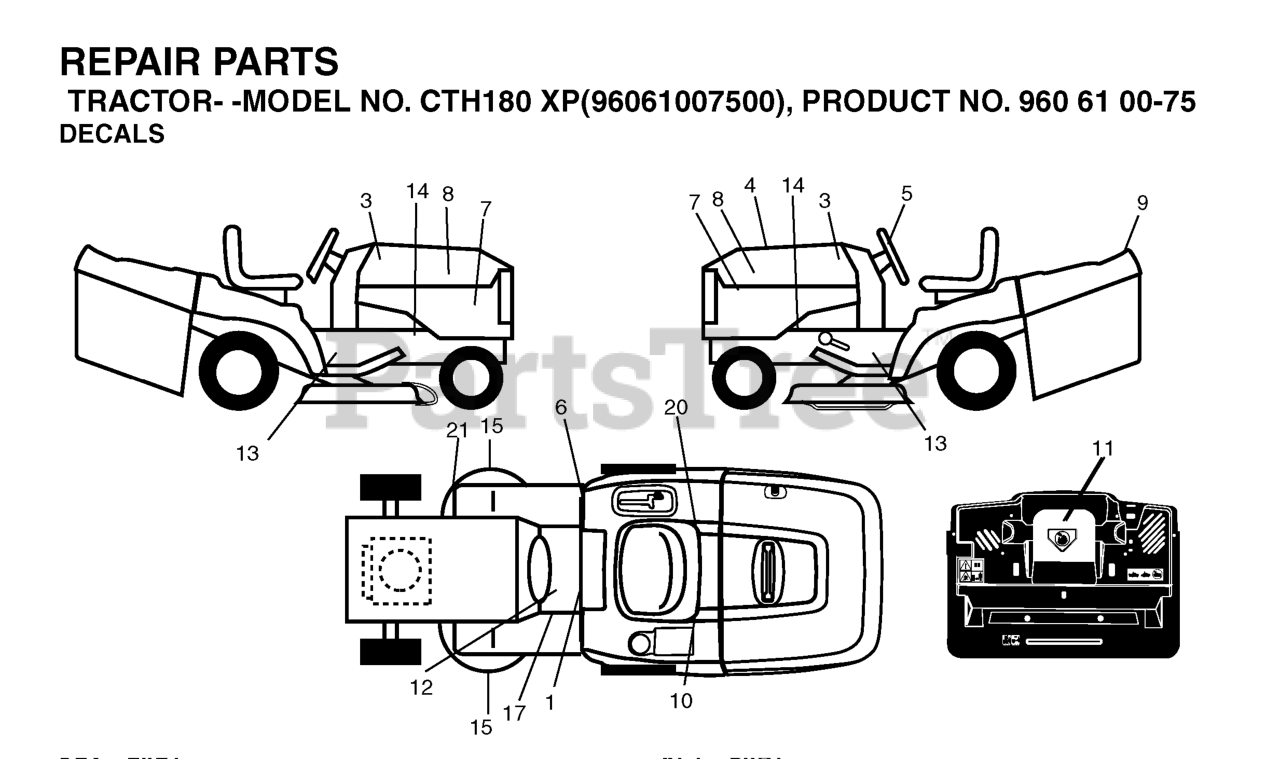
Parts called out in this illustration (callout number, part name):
1	LABEL
5	DECAL.STEERING.HUSQ.BLUE
6	Decal, Fender 100 DB/CE
8	DECAL.HOOD.HUSQVARNA.INTERNATI
10	DECAL BTRY SYMBOLS
11	DECAL.INTERNATIONL.CUTFINGER
12	DECAL
17	DECAL PARK BRAKE
20	DECAL.BYPASS.FENDER.CRD.LT.YT
